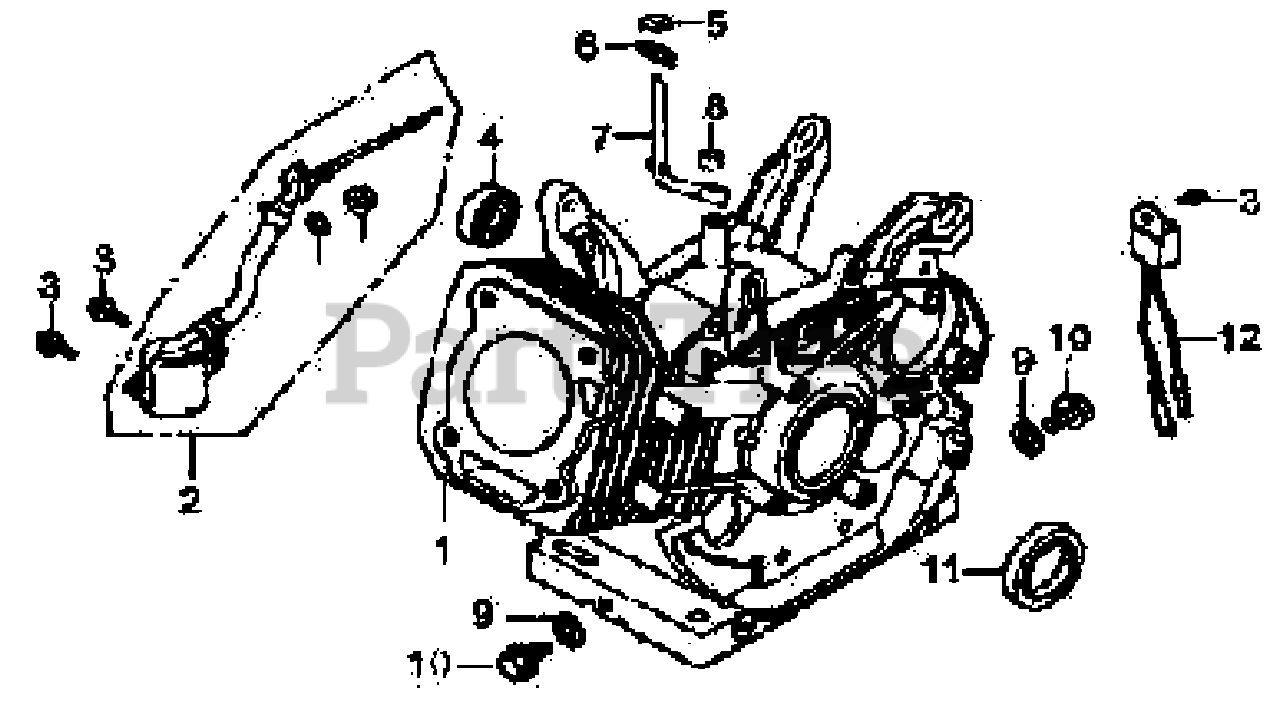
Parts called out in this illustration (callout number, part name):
1	CRANKCASE
2	SWITCH ASSY., OIL LEVEL
3	BOLT, FLANGEM6×12
4	BEARING, RADIAL BALL 6202
5	WASHER, PLAIN 8×16×1.2
6	PIN, LOCK
7	SHAFT, GOVERNOR ARM
8	OIL SEAL 8×14×4
9	WASHER, DRAIN PLUG12×20×2
10	BOLT, DRAIN PLUG M12×1.5×15
11	OIL SEAL 35×52×7
12	MODLE LOS
